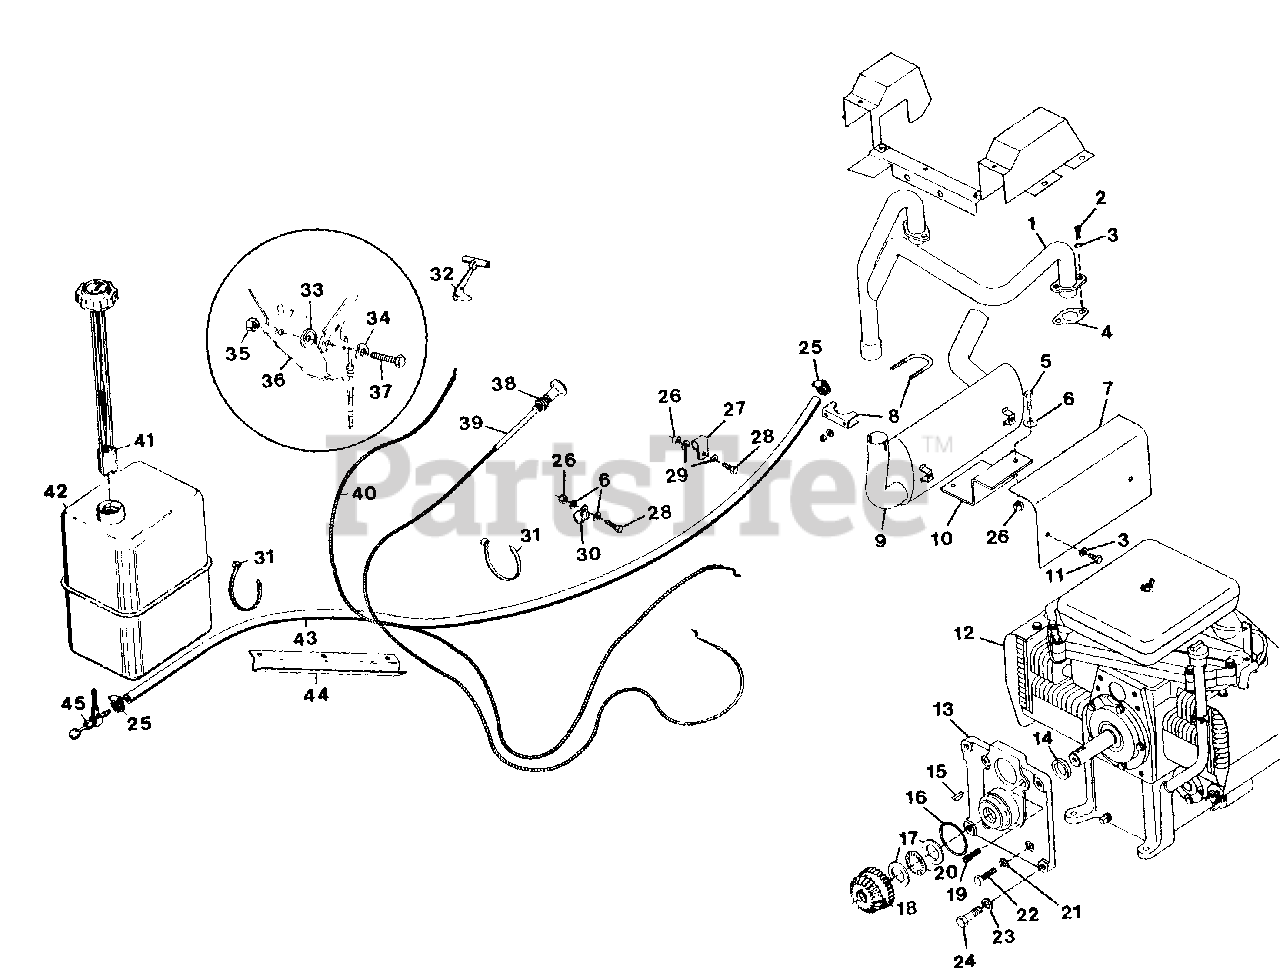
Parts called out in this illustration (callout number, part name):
1	HEADER, EXHAUST
2	SCREW, CAP 5/16-18X.75 SHD
3	WASHER, LOCK 5/16 REG.
4	GASKET, EXHAUST
5	BOLT, HEX 5/16-18X1.25
6	WASHER, FLAT .343X.688X.065
7	SHIELD, MUFFLER
8	CLAMP, MUFFLER U-BOLT
9	MUFFLER, EXHAUST
10	BRACKET, MUFFLER SUPPORT
11	BOLT, HEX 5/16-18X.75
12	ENGINE, 24 H.P. ONAN
13	ADAPTOR, ENGINE
14	SEAL, OIL 1.125X1.628X.250
15	KEY, WOODRUFF .25X1.125 SFT.
16	O-RING, 3.000X3.188X.094
17	RACE, BRG THRUST 1.125X1.75X.123
18	GEAR, SPUR AND BEVEL, INPUT
19	SCREW, CAP 3/8-16X1.75 HSHD
20	BEARING, THRUST 1.127X1.740X.078
21	WASHER, LOCK 3/8 REG.
22	BOLT, HEX 3/8-16X1.75
23	WASHER, LOCK 1/2 REG.
24	BOLT, HEX 1/2-13X1.75
25	CLAMP, HOSE
26	NUT, LOCK 5/16-18
27	CLAMP, NYLON 1.23
28	BOLT, HEX 5/16-18X1.00
29	WASHER, FLAT .313X.875X.065
30	CLAMP, STEEL .625
31	TIE, CABLE
32	ASSEMBLY, KNOB AND LEVER
33	WASHER, FRICTION
34	WASHER, SPRING
35	NUT, LOCK 1/4-28
36	BRACKET, MOUNTING
37	BOLT, HEX 1/4-28X.75
38	NUT, JAM 3/8-24 HEX
39	CONTROL, CHOKE
40	ASSEMBLY, CHOKE CONDUIT
41	GAUGE, GAS
42	TANK, FUEL
43	LINE, FUEL
44	SHIELD, HEAT
45	VALVE, FUEL 90 DEG. REV. FLOW
NS	SCREW, MACHINE 10-32X.50 PHD
NS	NUT, LOCK 10-32
